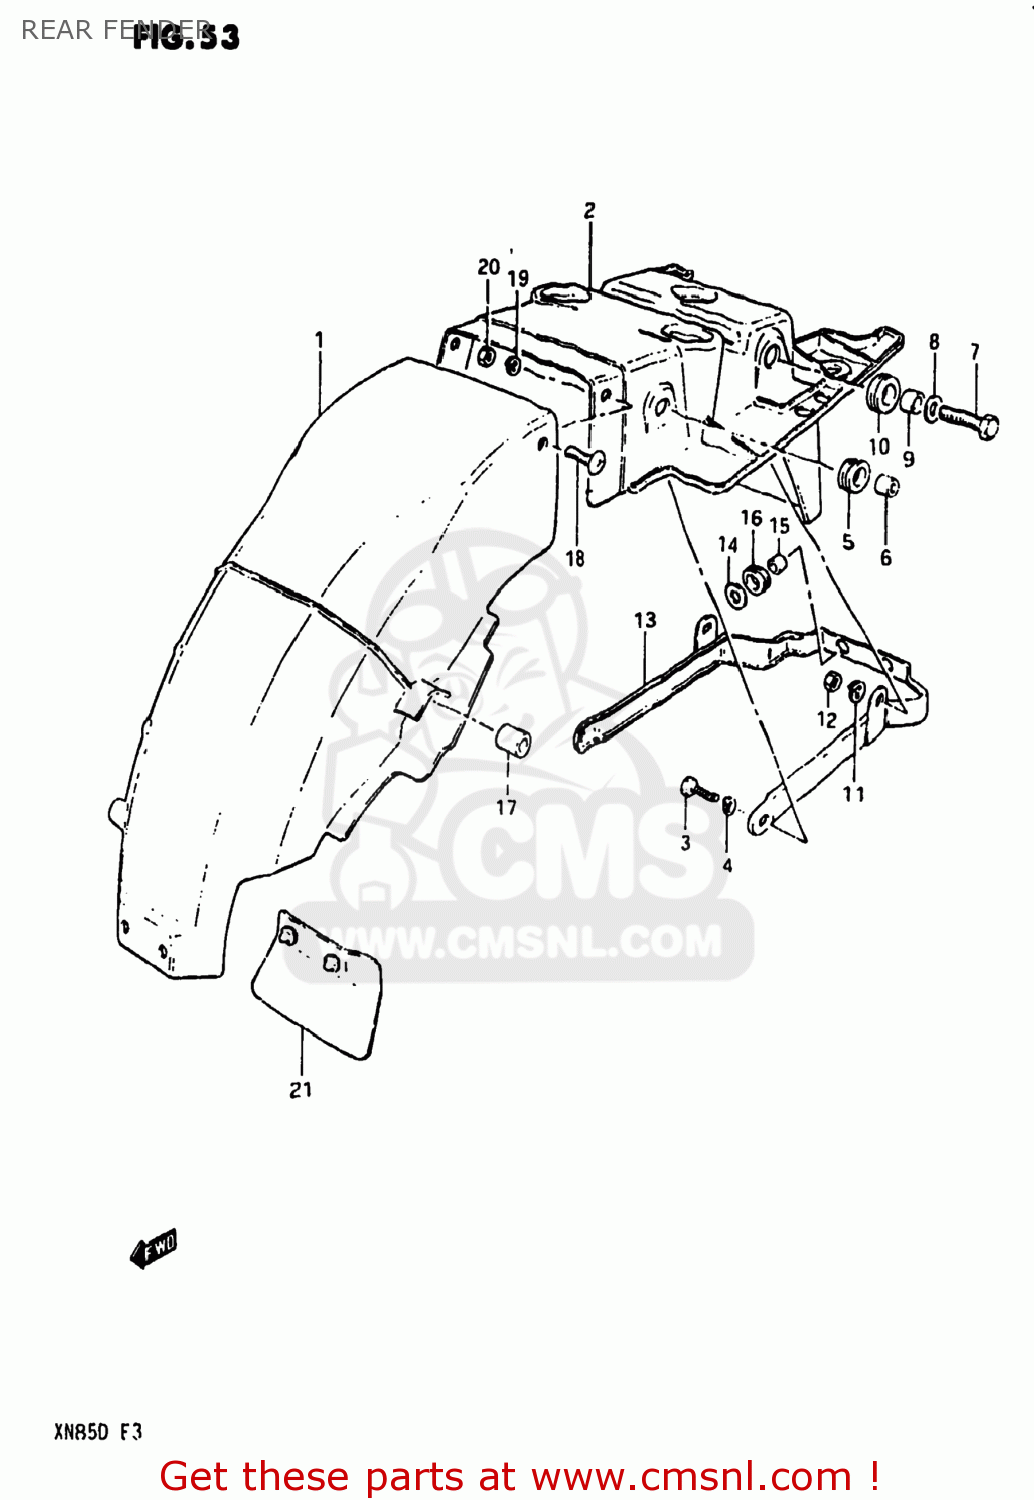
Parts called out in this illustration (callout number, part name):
1	FENDER,REAR
2	BODY,REAR FENDER,REAR
3	BOLT
4	LOCK WASHER
5	CUSHION
6	SPACER(6.1X9X7.5)
7	BOLT (8X30)
8	WASHER
9	SPACER (8.2X12X7.5)
10	CUSHION
11	LOCK WASHER
12	NUT
13	REINFORCEMENT,REAR FENDER
14	WASHER(6,5X22X1.6)
15	SPACER (6.1X9X9)
16	CUSHION
17	CUSHION
18	SCREW
19	WASHER (5.5X16X1.2)
20	NUT
21	GUIDE,RR FENDER MUD
